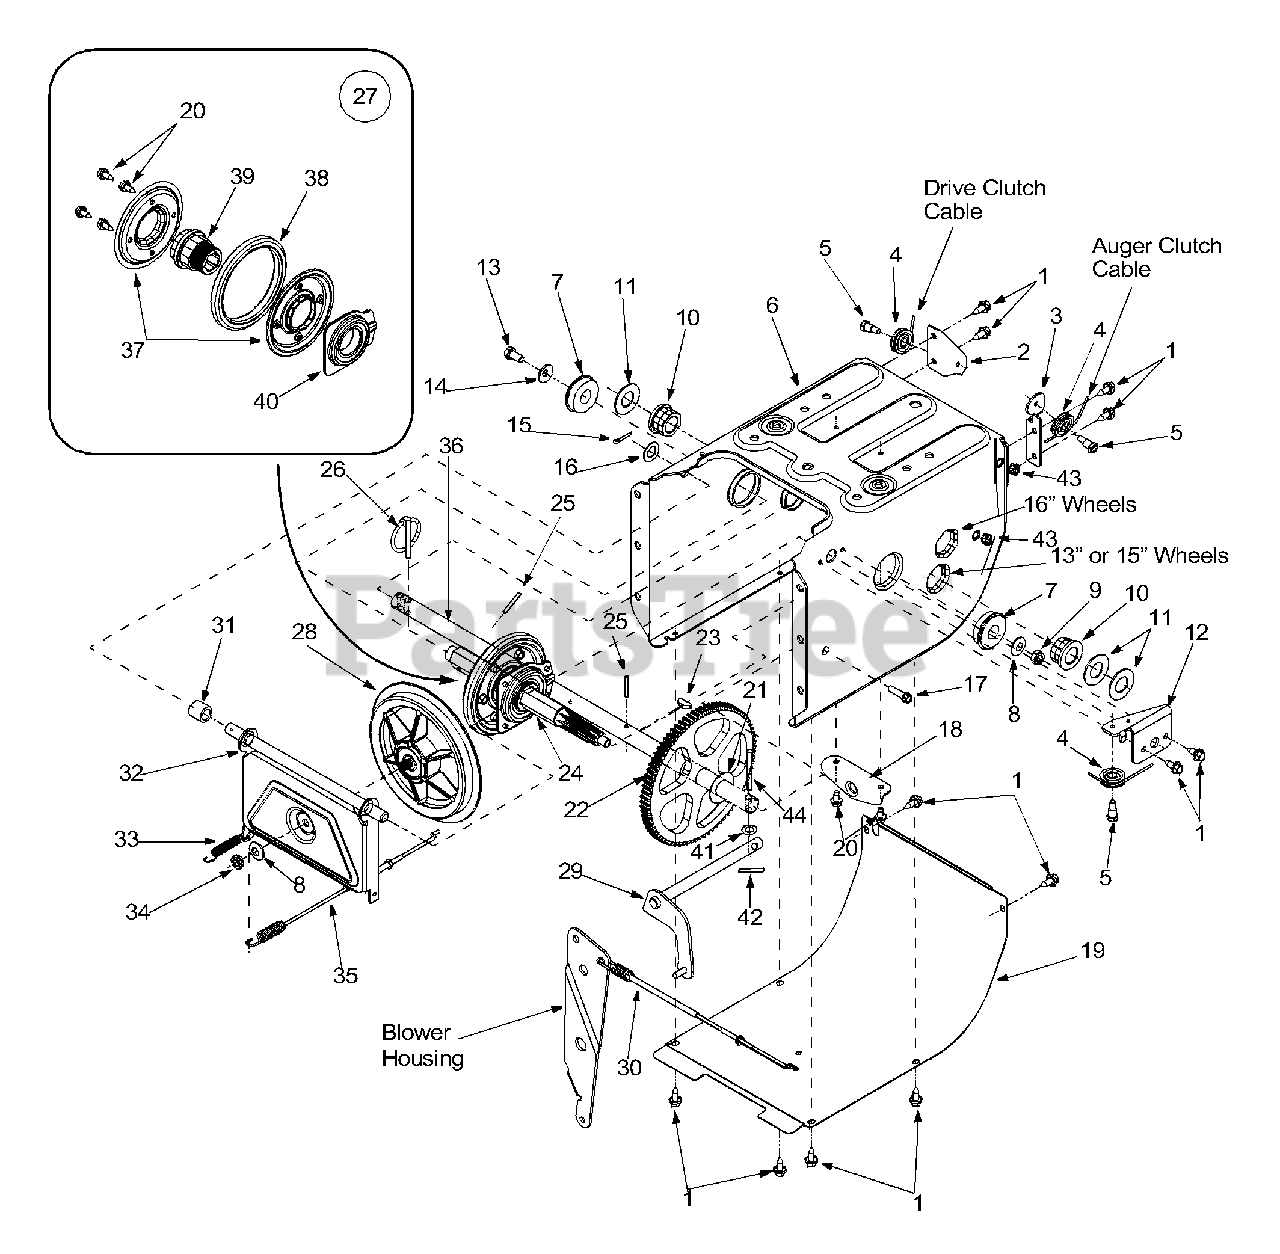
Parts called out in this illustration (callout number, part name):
1	Hex Screw
5	Hex Screw 1/4-28
6	Frame Assembly
7	Ball Bearing
8	Bell Washer
9	Lock Jam Nut
10	Hex Flange Bearing
11	Flat Washer
14	Bell Washer .340 ID x .872 OD
15	Cotter Pin
16	Flat Washer .536 ID x .930 OD
17	Hex Washer Screw 1/4-20
21	Flat Washer .760 ID x .50 OD
24	7-Tooth Shaft
25	Roll Pin
26	Klik Pin
27	Friction Wheel Assembly
28	Friction Disc Wheel
29	Wheel Shift Rod Assembly
30	Drive Cable
31	Spacer
34	Jam Nut 3/8-24
35	Drive Cable
36	Axle 13" Wheels
37	Friction Plate
38	Friction Wheel Rubber
39	Friction Wheel Hub
40	Friction Wheel Bearing
41	Flat Washer .281 I.D. x .50 O.D.
42	Cotter Pin
43	Insert Jam Nut 5/16-18
44	Clevis Pin, 1/4 x 1.3725
